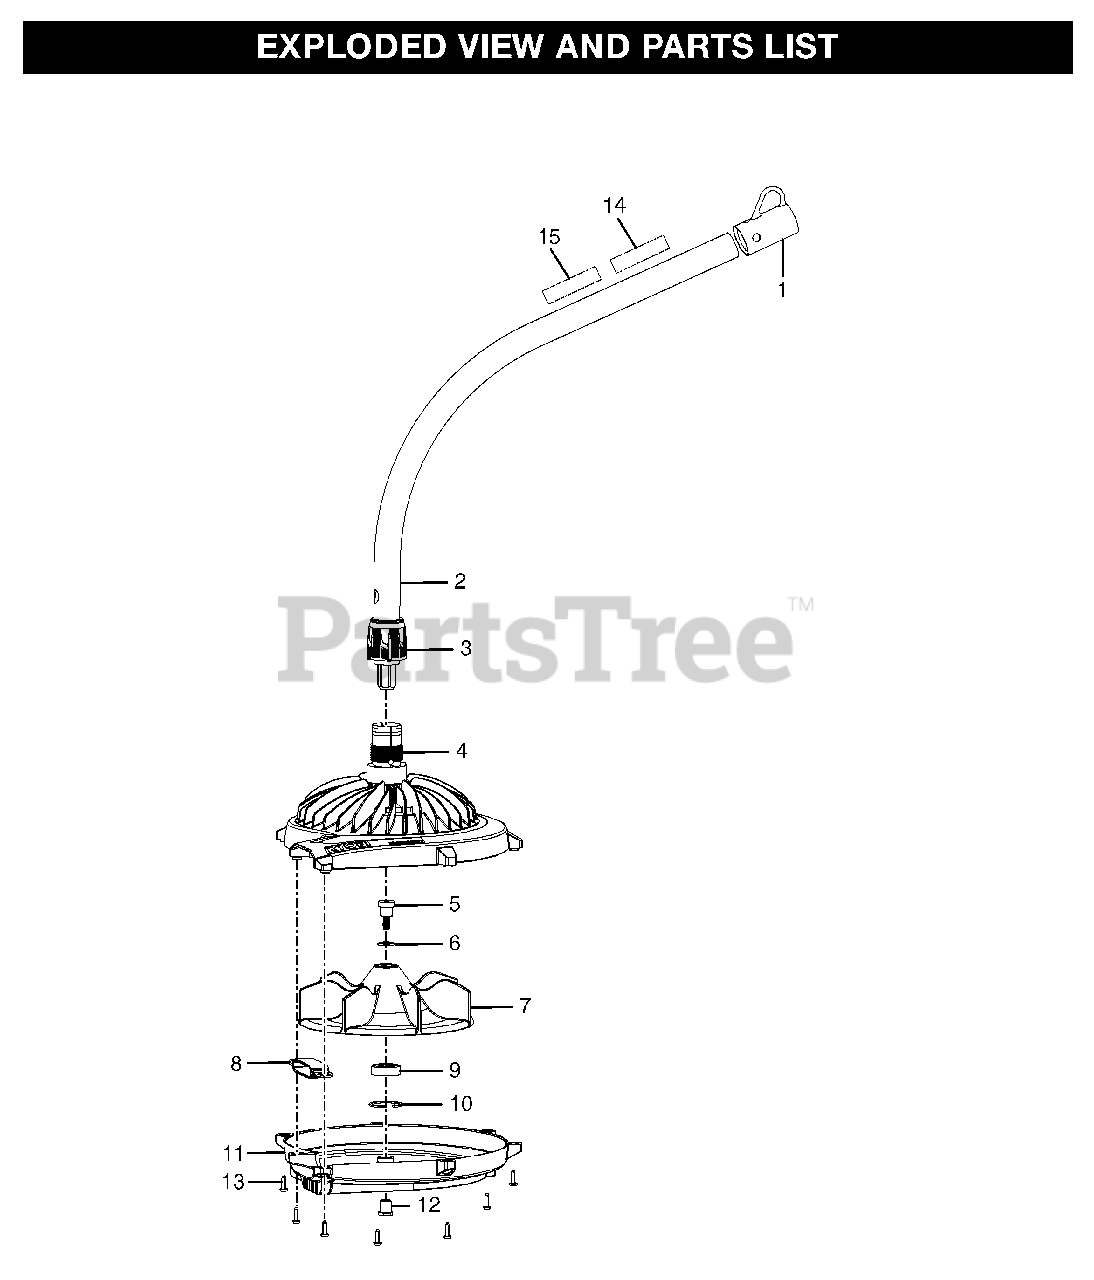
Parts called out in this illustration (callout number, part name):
1	Hanger Cap
2	Blower Attachment Shaft
3	Attachment Securing Cap
4	Upper Housing
5	Shoulder Bolt (M5 x 21 mm)
6	Lock Washer (M12)
7	Fan
9	Ball Bearing
11	Lower Housing
12	Threaded Insert
13	Screw (M4 x 13 mm T.F.)
14	Warning Label
15	Logo Label
